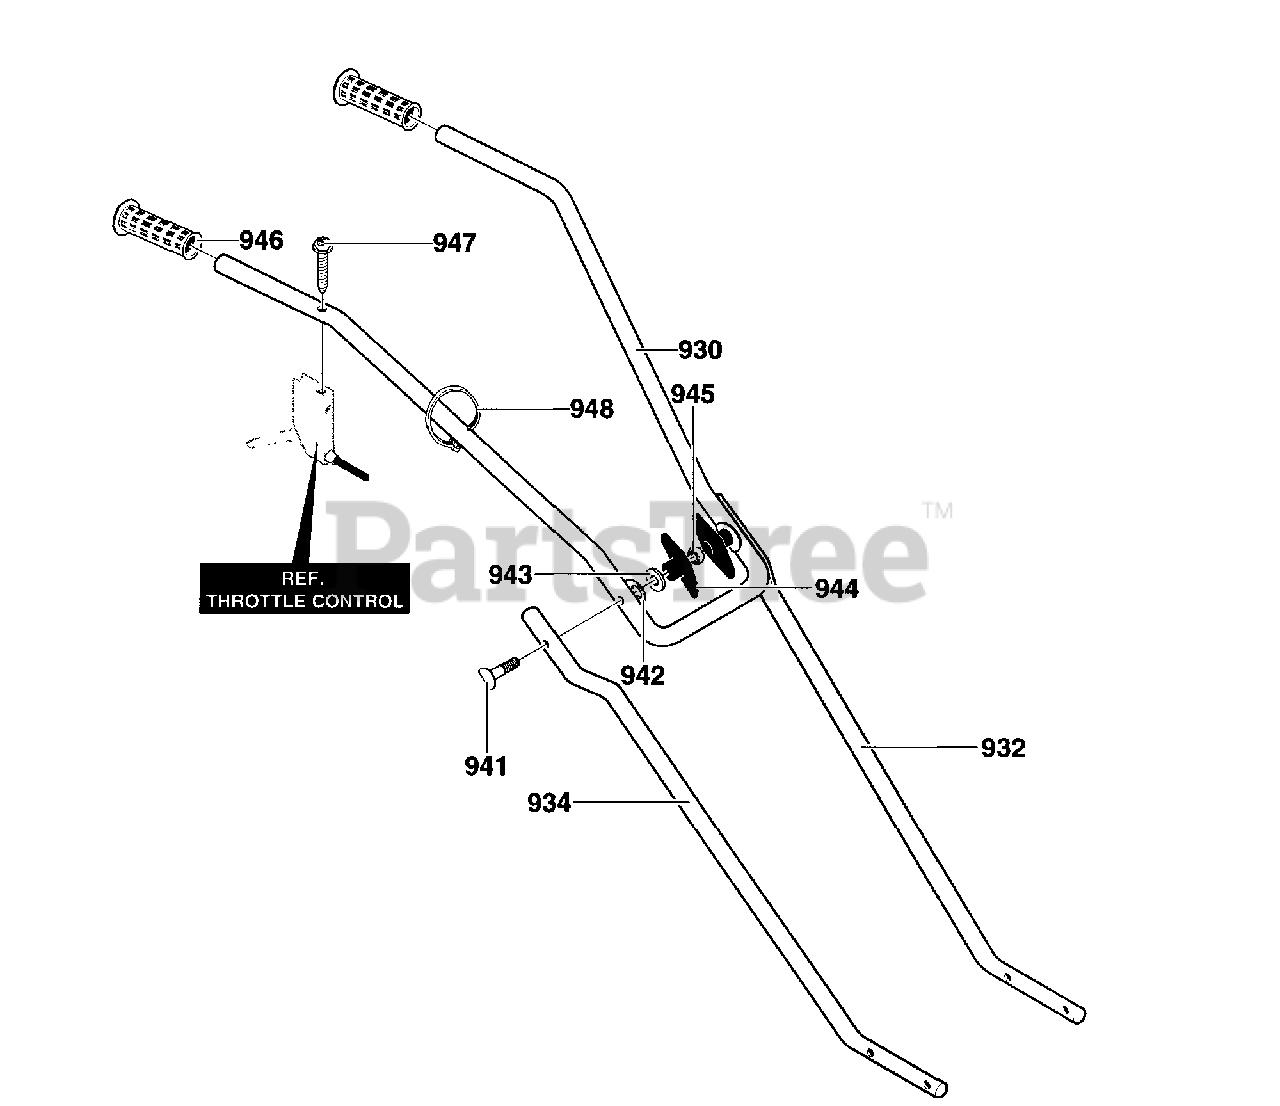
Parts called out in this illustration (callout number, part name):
930	HANDLE, UPPER .75X18GASTEEL
932	HDL, LOWER LH
934	HDL, LOWER RH
941	BOLT, 5/16-18X1.63 CARRSP
942	WASHER,.343IDX1.OX.062 FORM
943	WASHER, FLAT .344X .69X 065
944	KNOB, T 2BLADE W/516/18 NUT
945	NUT, 5/16-18 REGHEX
946	GRIP, HAND
947	SCREW, 10-16X1.50 WAHHTAP
948	TIE, CABLE BLACK NYLON 5.62L
